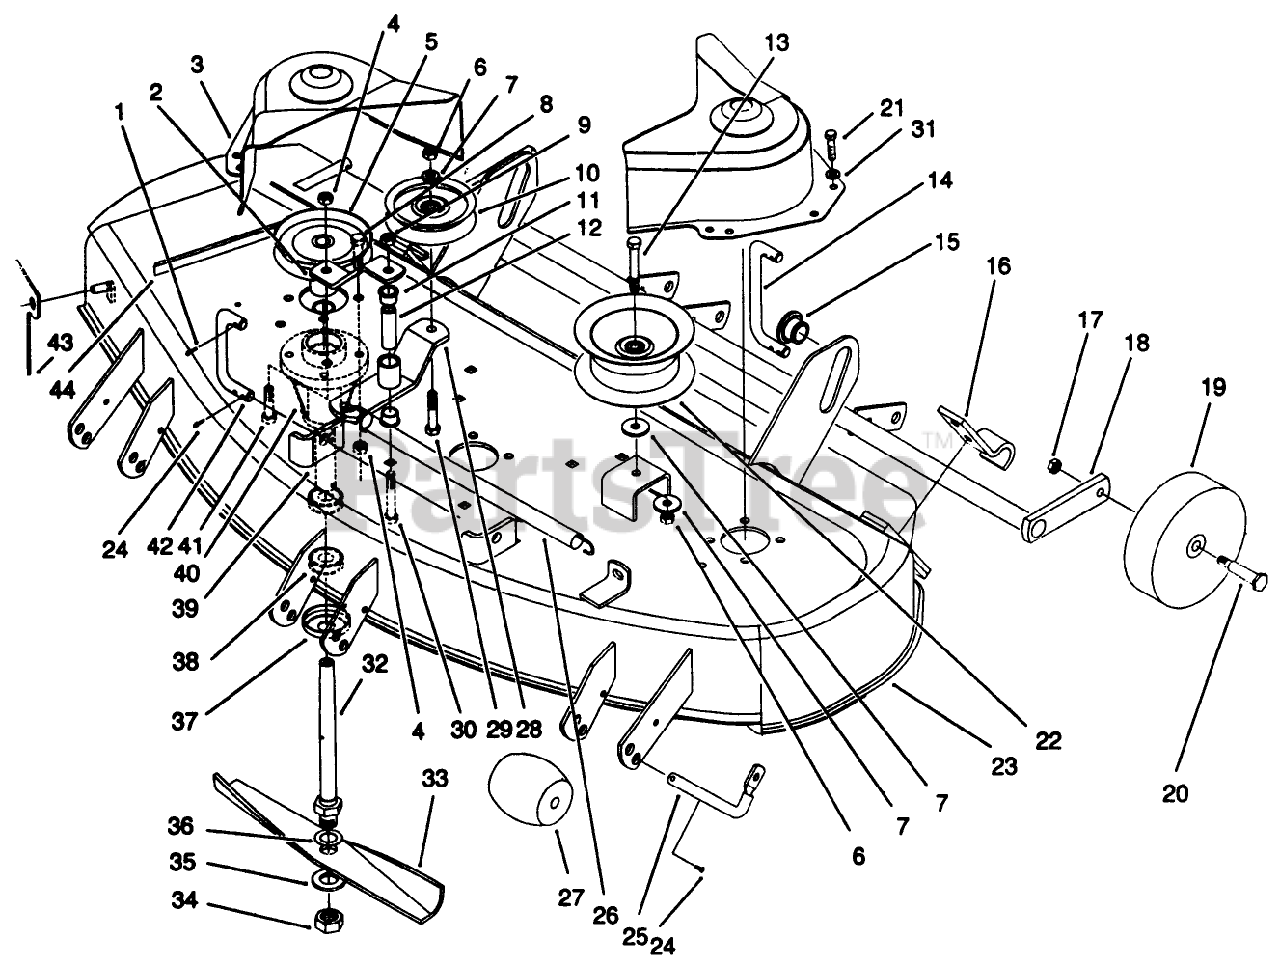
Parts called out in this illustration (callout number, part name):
1	Hairpin
2	Strap-Brace
3	COVER-BELT
4	NUT
5	Pulley-Spindle
6	NUT
7	Washer
8	Bolt
9	NUT
10	Pulley-Idler
11	BUSHING
12	SPACER-2.0 LG R
13	Bolt
14	LINK-REAR
15	ROLLER-LIFT
16	Clamp
17	Nut
18	Gage Wheel Support W.A.
19	WHEEL
20	BOLT-SHOULDER
21	Bolt
22	Pulley-Idler
23	Deck W.A.
24	Cotter Pin
25	SHAFT-ROLLER
26	SPRING - EXTENSION
27	ROLLER
28	Arm-Idler
29	Bolt
30	Screw-Hex. Hd.
32	SHAFT-SPINDLE
33	14IN BLADE KIT
34	Nut
35	Washer
36	Washer
37	CUP-SPINDLE
38	BEARING-BALL
40	HOUSING-SPINDLE
41	BOLT
42	LINK-FRONT
43	Chute Extension
44	Belt
